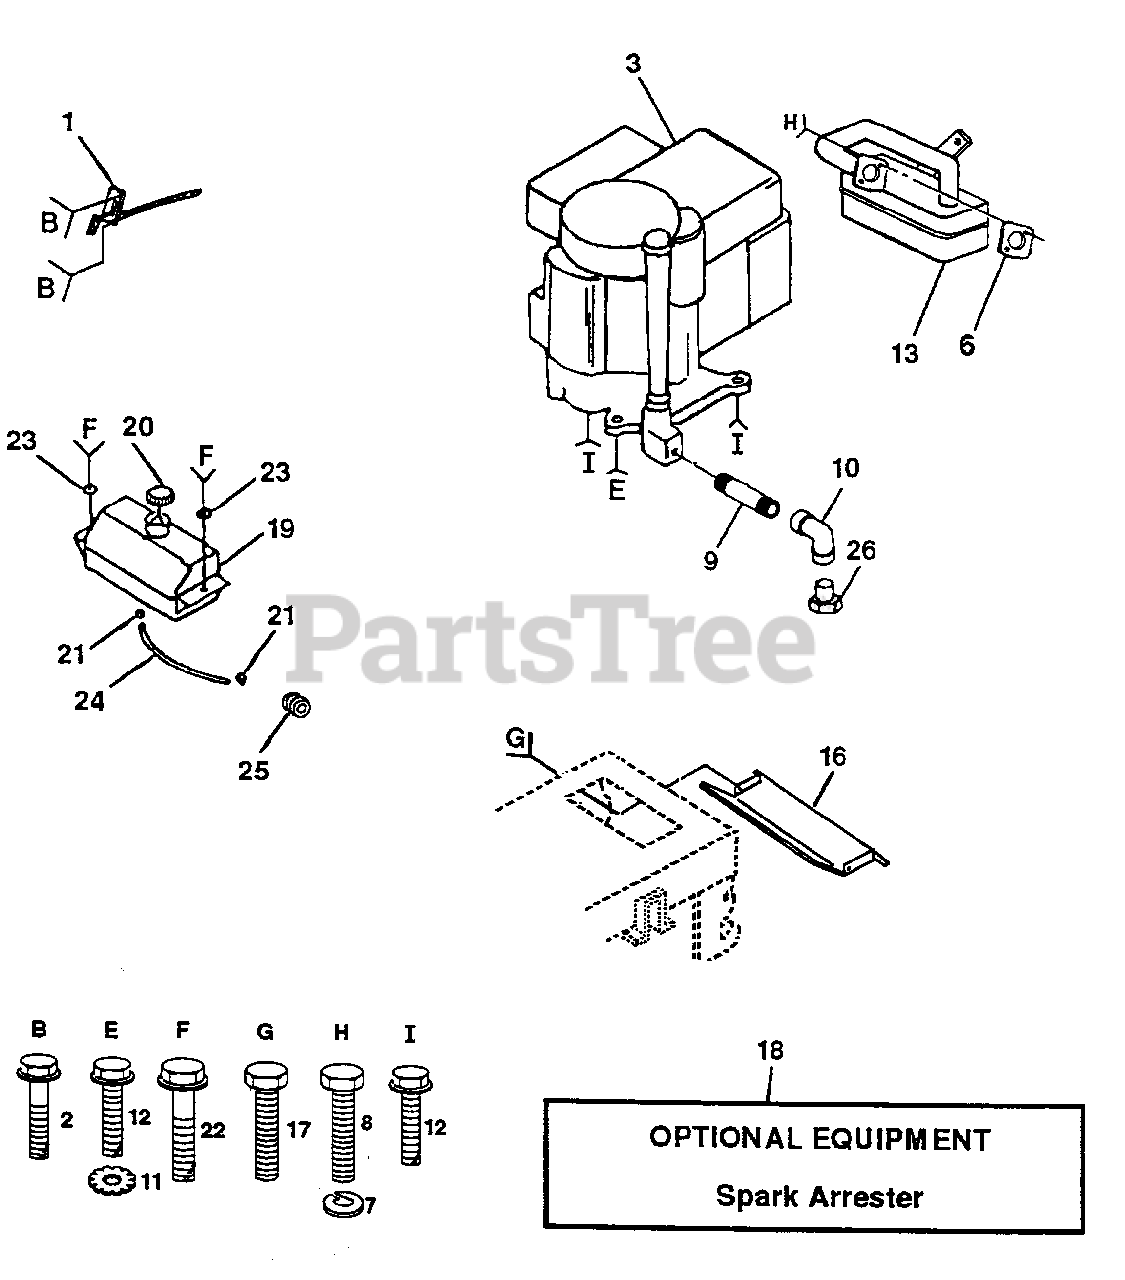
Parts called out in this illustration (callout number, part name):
1	Control Th/ch RH Blk Tee 15 10
2	Screw Hex Thd Cut 1/4-20x5/8 T
6	Gasket Eng 1 313 Id Tin Plated
7	Washer Lock Hvy HlcI Spr 5/16
8	Screw Hexhd Cap 5/16-18x 3/4
9	Nipple Pipe 3/8 Npt X 3"
10	Elbow Std 90 Degree 3/8-18 Npt
11	Washer Lock Ext Tooth 3/8
12	Screw Thdrol 3/8-16x1-1/4 TYTT
13	Muffler LT B&S 12/12 5 HP
16	Shield Heat Browning LT/YT
17	Screw Tap Hex #10-24unc X 1/2
18	Kit Spark Arrestor (Flat Scrn)
19	Tank Fuel Front 1 25
20	Cap Asm Fuel W/sym Vented
21	Clamp Hose Blk
22	Screw Hexwsh Thdrol 1/4-20x3/4
23	Washer 9/32 X 7/8 X 16 Ga
24	Line Fuel 13"
25	Bushing Snap Nyl Blk Fuel Line
